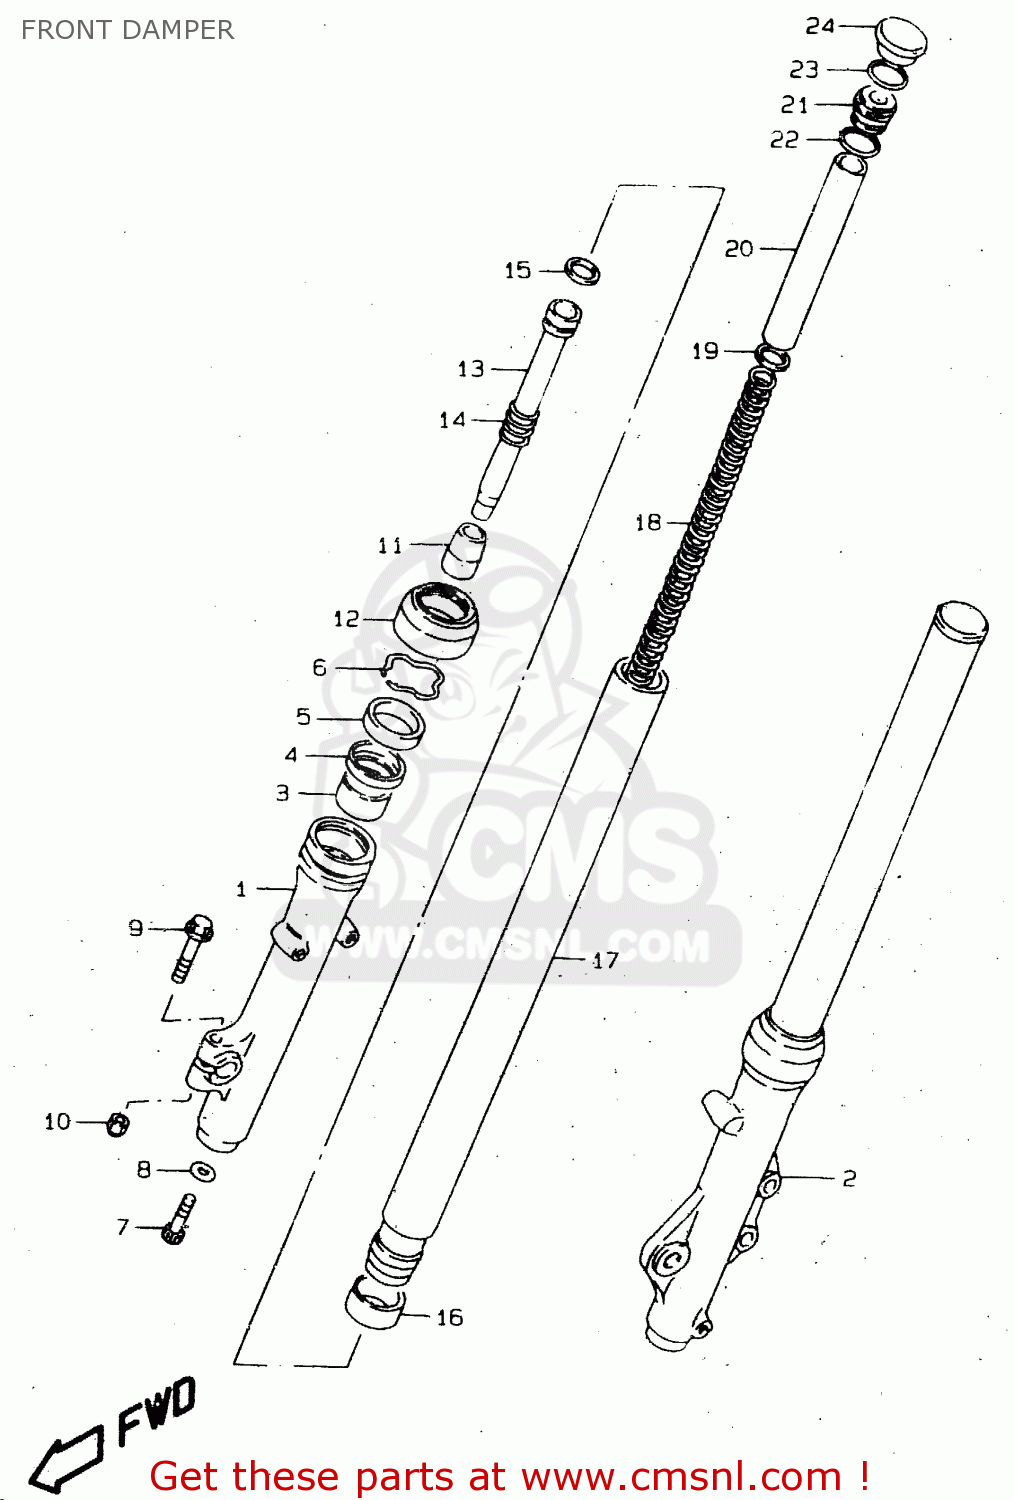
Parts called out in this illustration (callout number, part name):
1	TUBE,OUTER,R
2	TUBE,OUTER,L
3	BUSH,GUIDE
4	SPACER
5	SEAL,OIL
6	RING,OIL SEAL STOPPER
7	BOLT(8X27)
8	GASKET (NAS)
9	BOLT
10	NUT
11	PIECE,OIL LOCK
12	DUST SEAL
13	CYLINDER
14	SPRING,REBOUND
15	RING,PISTON
16	BUSH
17	TUBE,INNER
18	SPRING
19	SEAT,SPRING
20	SPACER,FRONT FORK SPRING
21	SEAT,SPRING
22	O RING
23	RING,STOPPER
24	CAP
